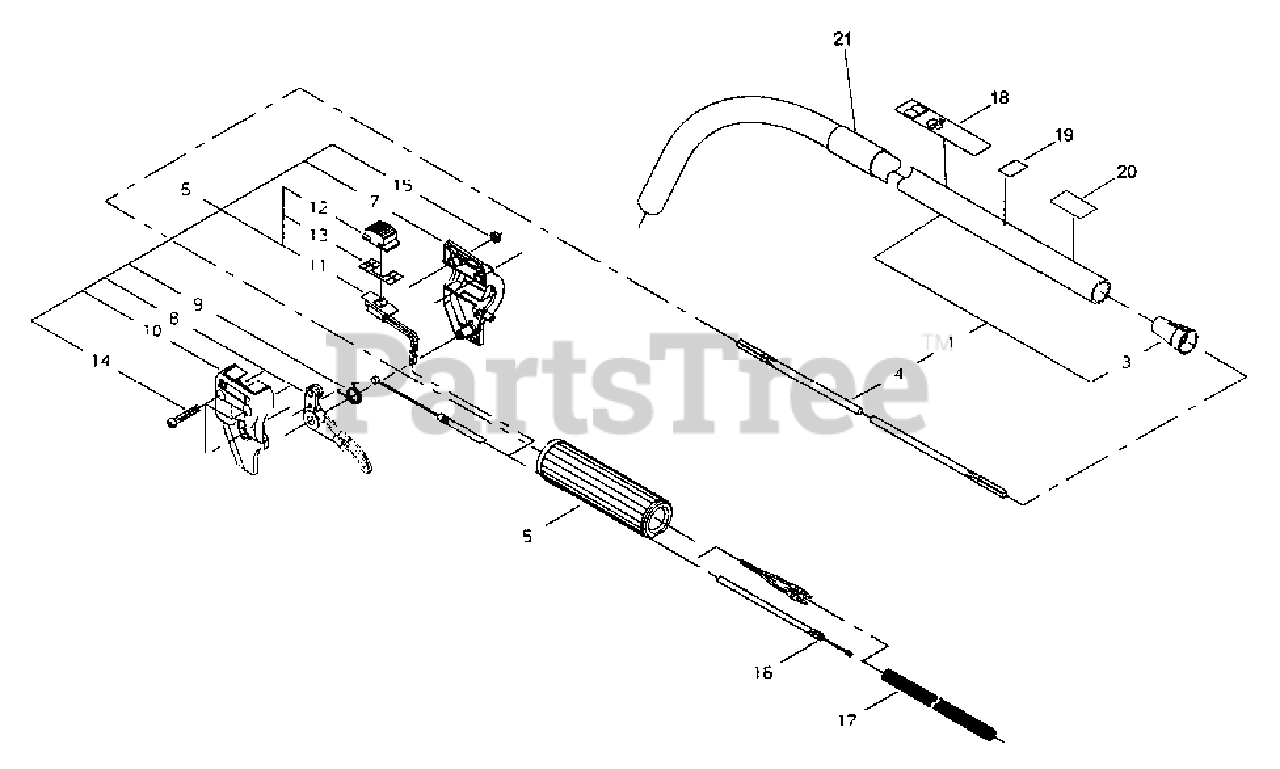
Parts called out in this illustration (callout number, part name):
1	MAIN PIPE ASSY
4	DRIVESHAFT - FLEXIBLE
5	GRIP
6	THROTTLE LEVER ASSY
7	BRACKET - RIGHT
8	TRIGGER, THROTTLE
9	SPRING, TRIGGER
10	HANDLE, CONTROL - LEFT
11	SWITCH
12	KNOB
13	PLATE, SWITCH
14	SCREW - 5X30
15	NUT - 5
16	CABLE, THROTTLE
17	TUBE
18	LABEL - CAUTION
19	LABEL - INSTRUCTION
20	LABEL - OUTER TUBE
